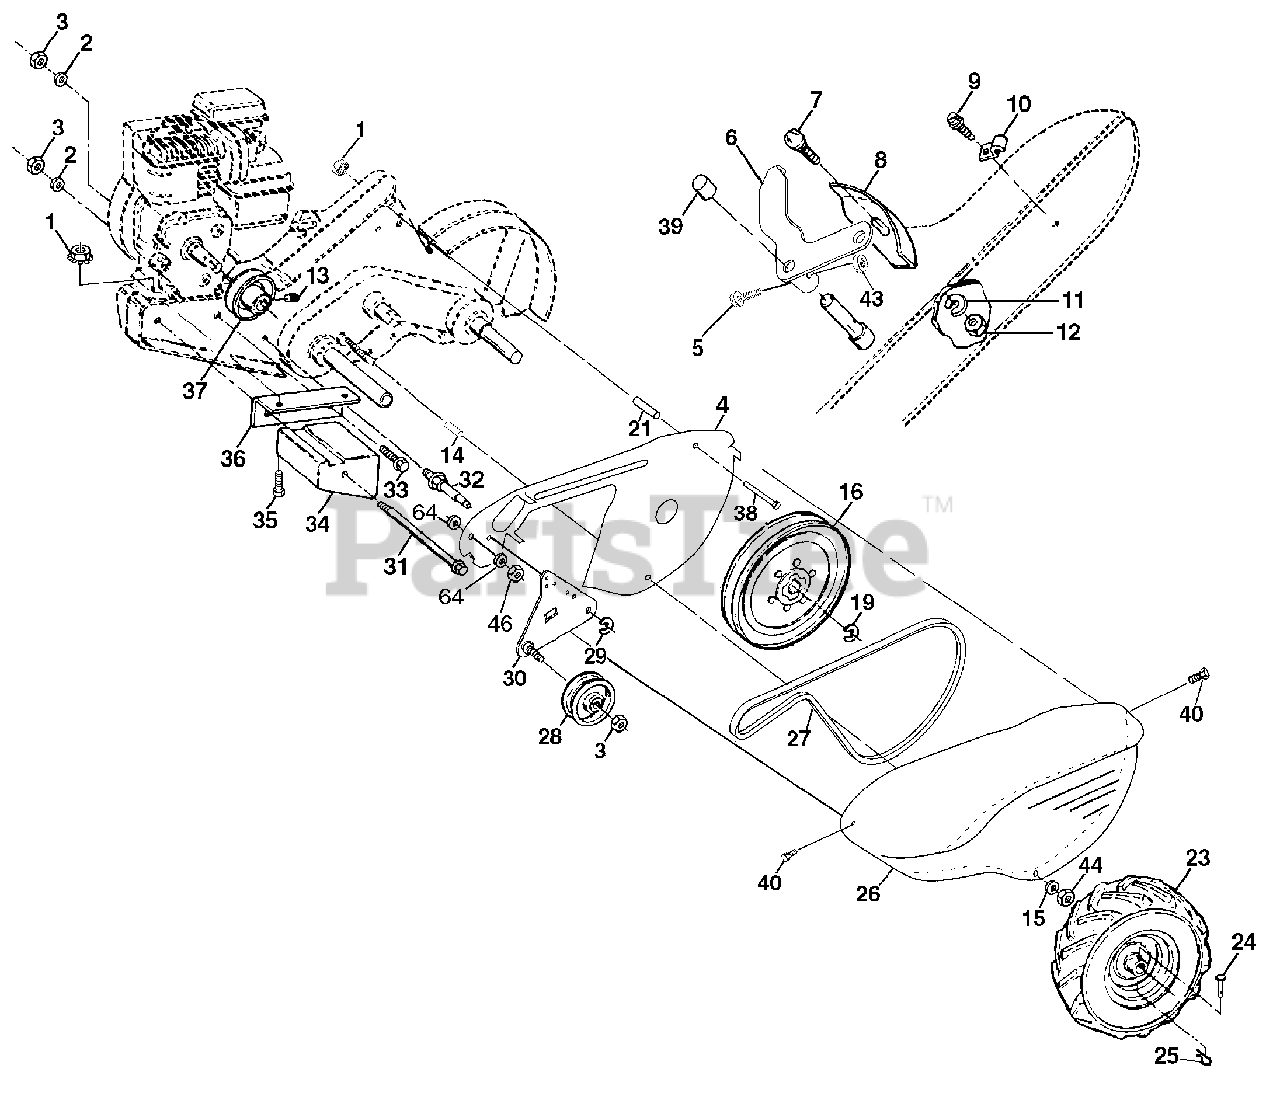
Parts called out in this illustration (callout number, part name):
1	Nut, Keps 5/16-18
2	Washer, Lock 3/8
3	Nut, Hex 3/8-16
4	Shield Inner Belt Guard
5	Screw Shift Lever
6	Lever, Shift
7	Bolt, Carriage 1/4-20 x 1/2 Gr. 5
8	Plate, Shift Indicator
9	Screw, Hex, Washer Head, Slotted #10-24 x 1/2
10	Clip
11	Washer, Lock 1/4
12	Nut, Hex 1/4-20
13	Screw, Set, Hex 5/16-18 x 3/8
14	Spacer, Split 0.327 x 0.42 x 1.220
15	Washer 11/32 x 11/16 x 16 Ga.
16	Sheave, Transmission
19	Ring, Retainer
21	Spacer, Split 0.327 x 0.42 x 2.09
22	Bolt Fin Hex 5/16-24 x 1/2
23	Tire
23	Rim
23	Tire Valve
24	Rivet, Drilled
25	Clip, Hairpin
26	Guard, Belt
27	Belt, V
28	Pulley, Idler
29	Ring, Klip
30	Bracket, Idler
31	Bolt, Hex 5/16-16 x 12
32	Shaft, Idler Arm
33	Bolt, Hex 3/8-16 x 1
34	Counterweight, L. H.
35	Bolt, Hex 5/16-18 x 1-1/2
36	Bracket, Reinforcement, L. H.
37	Sheave, Engine
38	Bolt Fin Hex 5/16-18 x 2-3/4
39	Cap, Plunger Blk
40	Screw Hex Wsh. Slt #10-24 x .50
43	Nut Lock #10-24
44	Nut Lock Hx W/Ins 5/16-18
